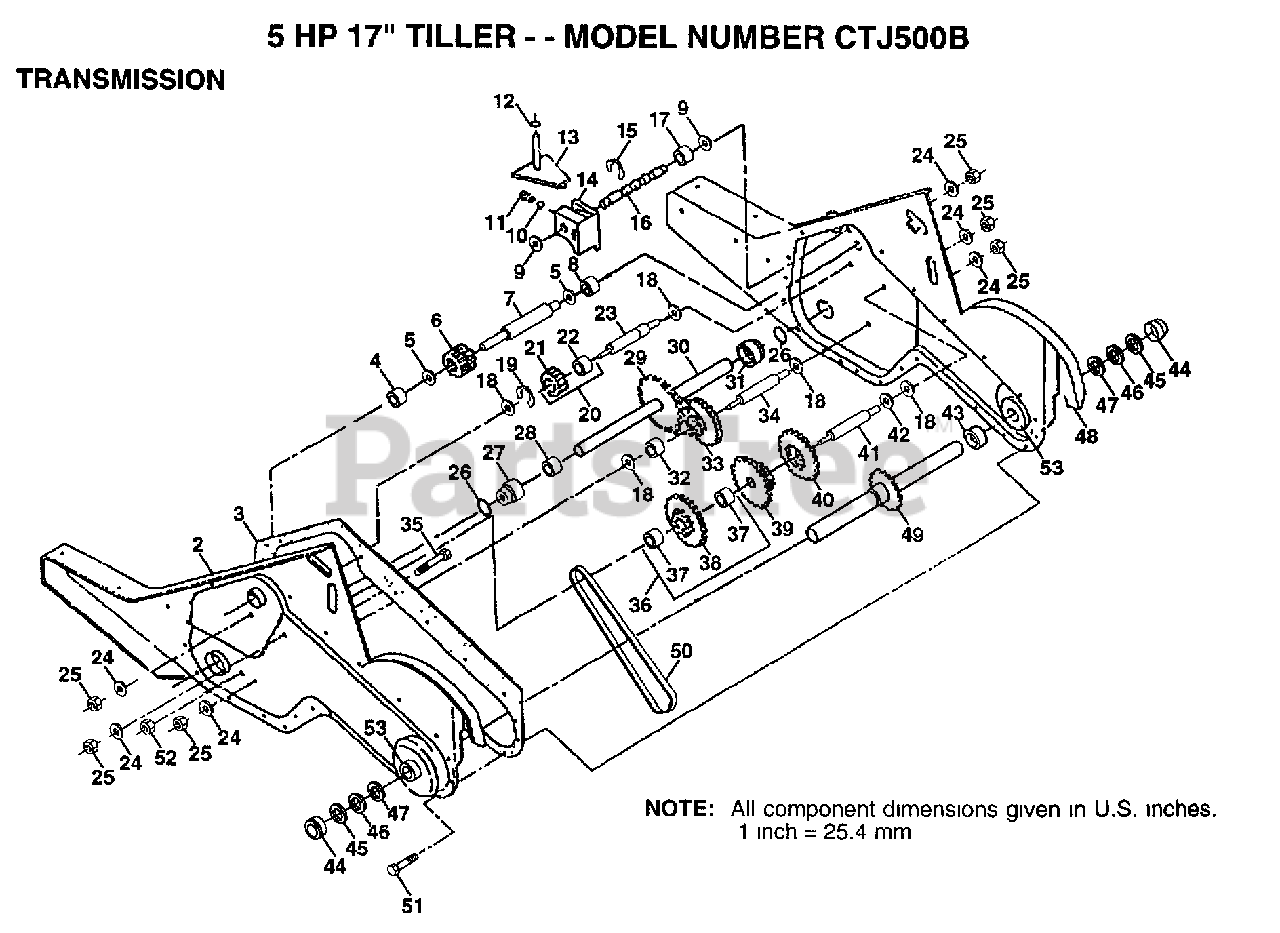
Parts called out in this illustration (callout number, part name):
3	GASKET TI
4	NEEDLE BRNG LT
5	"T, BEARING"
6	PINION-INPUT CRT
7	SHAFT-INPUT CRT
8	"TI, BEARING"
9	WASHER SEAL CRT
11	SPRING-SHIFT CRT
12	O-RING TI
13	ARM ASSY CRT
14	SHIFT FORK TI
15	KLIP RING
16	SHAFT SHIFT CRT
17	SPACER SPLIT CRT
18	WASHER
19	KLIP RING
20	GEAR ASSY CRT
21	GEAR-REV IDLR CRT
22	NEEDLE BEARING TI
23	SHAFT CRT
24	LOCKWASHER
25	NUT.ASF.HEX.7/16
26	O RING CRT
27	"CRT, BEARING"
28	BUSHING TI
29	CHAIN CRT
32	SPACER TI
33	SPRCKT 8 GEAR CRT
34	SHFT 2ND RED. CRT
35	SCRW WHIZ LOK CRT
36	SPROCKET ASM.
37	BEARING
39	GEAR TI
40	GEAR TI
41	REDUCTION SHFT TI
42	BRNG RACE
43	SPACER TI
44	CUP.FORMED.
45	RING SPIRAL CRT
46	SEAL RING RUBBER
47	OIL SEAL STD
49	TINE SHAFT
50	CHAIN.50 LINK TI
51	SCREW CRT
52	NUT.HEX.5/16-18
